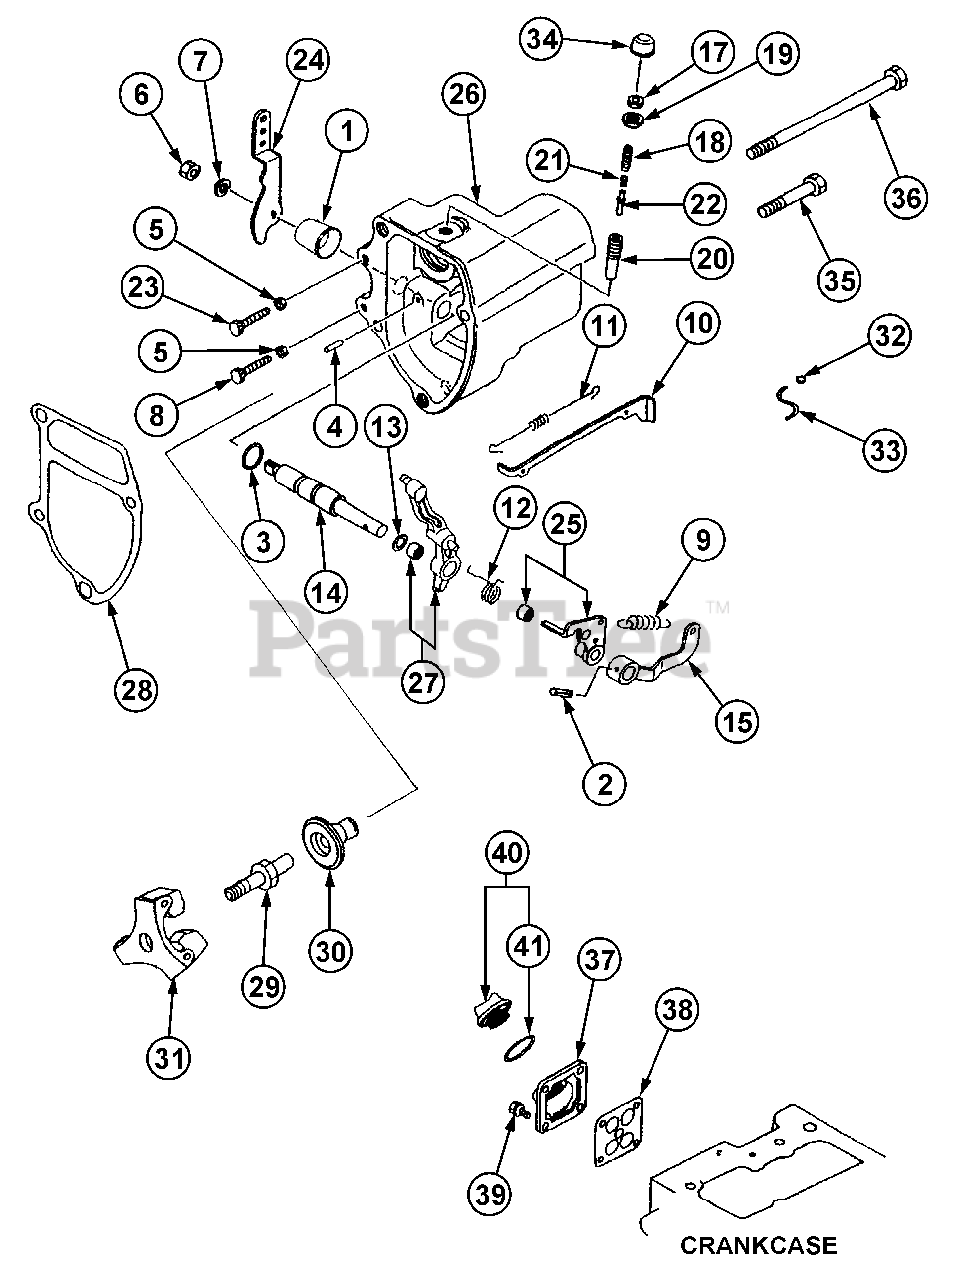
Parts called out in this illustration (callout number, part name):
1	Cover, Governor
2	Pin, Spring
3	O-Ring
4	Pin, Grooved
7	Washer, Spring
8	Bolt, Speed Set
11	Spring, Tie Rod
12	Spring, Start
13	Shim, Gov. Shaft
14	Shaft, Governor
15	Lever, Gov. Spring
18	Screw, Adjusting
19	Nut, Special
20	Case, Torque Spring
21	Spring, Torque
22	Stopper, Spring
23	Bolt, Low Idle Set
25	Lever Assy, Tension
26	Case, Governor
27	Lever Assy, Gov.
28	Gasket, Gov. Case
29	Shaft, Sleeve
30	Sleeve, Sliding
31	Weight Assy, Gov.
36	Bolt, Gov. Case
39	Bolt, w/Washer
40	Cap Assy
